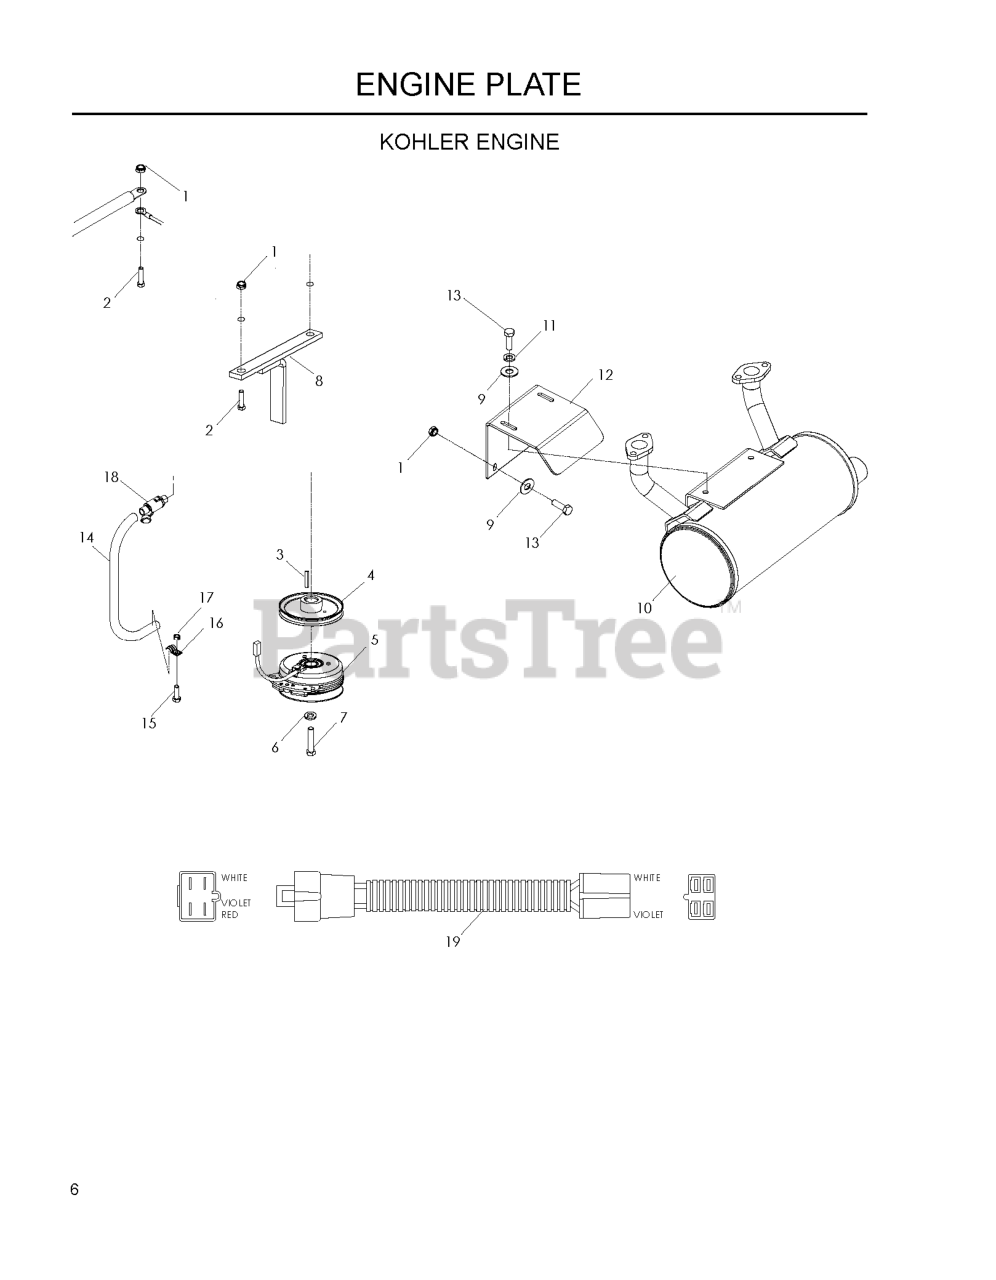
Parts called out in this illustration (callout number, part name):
1	NUT 5/16 NYLOC
2	HCS 5/16C X 1 3/4
3	KEY 1/4" SQ X 1 7/8"
5	ELECTRIC CLUTCH W/CABLE
6	WASHER 7/16 LOCK
7	BOLT 7/16F X 2 1/2
8	CLUTCH TIE DOWN
9	WASHER 5/16 FLAT
10	MUFFLER KOHLER GEN II
11	WASHER.LOCK.HVY.HLCL.SPR.5/16
12	MUFFLER BRACKET BLACK
13	HCS 5/16C X 1
14	OIL DRAIN HOSE
15	HCS 1/4C X 3/4 HCS
17	NUT 1/4C CENTER LOCK
18	OIL DRAIN FITTING
19	KOH PIGTAIL
